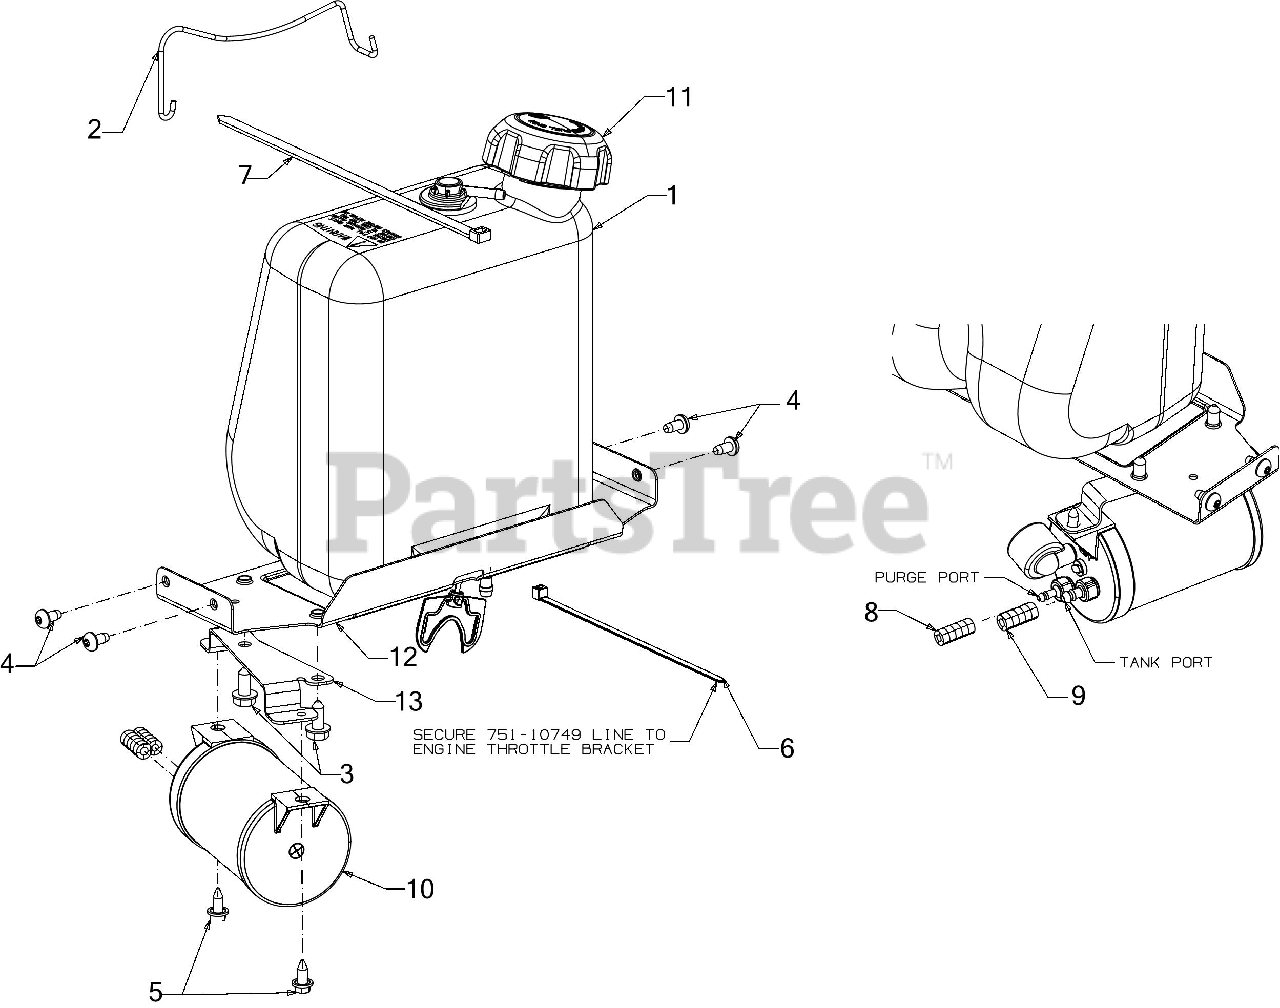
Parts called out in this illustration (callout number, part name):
1	FUEL TANK ASSEMBLY
2	BATTERY ROD ASSEMBLY
3	SCREW 5/16-18 x .750
4	SCREW 1/4-20 x .5
5	SCREW 1/4-20X.625
6	7" CABLE TIE
7	CABLE TIE 36"
8	FUEL HOSE LOW PERMEATION
9	FUEL HOSE LOW PERMEATION
10	CARBON CANISTER
11	FUEL CAP W/TETHER
12	FUEL TANK SUPPORT BRACKET
